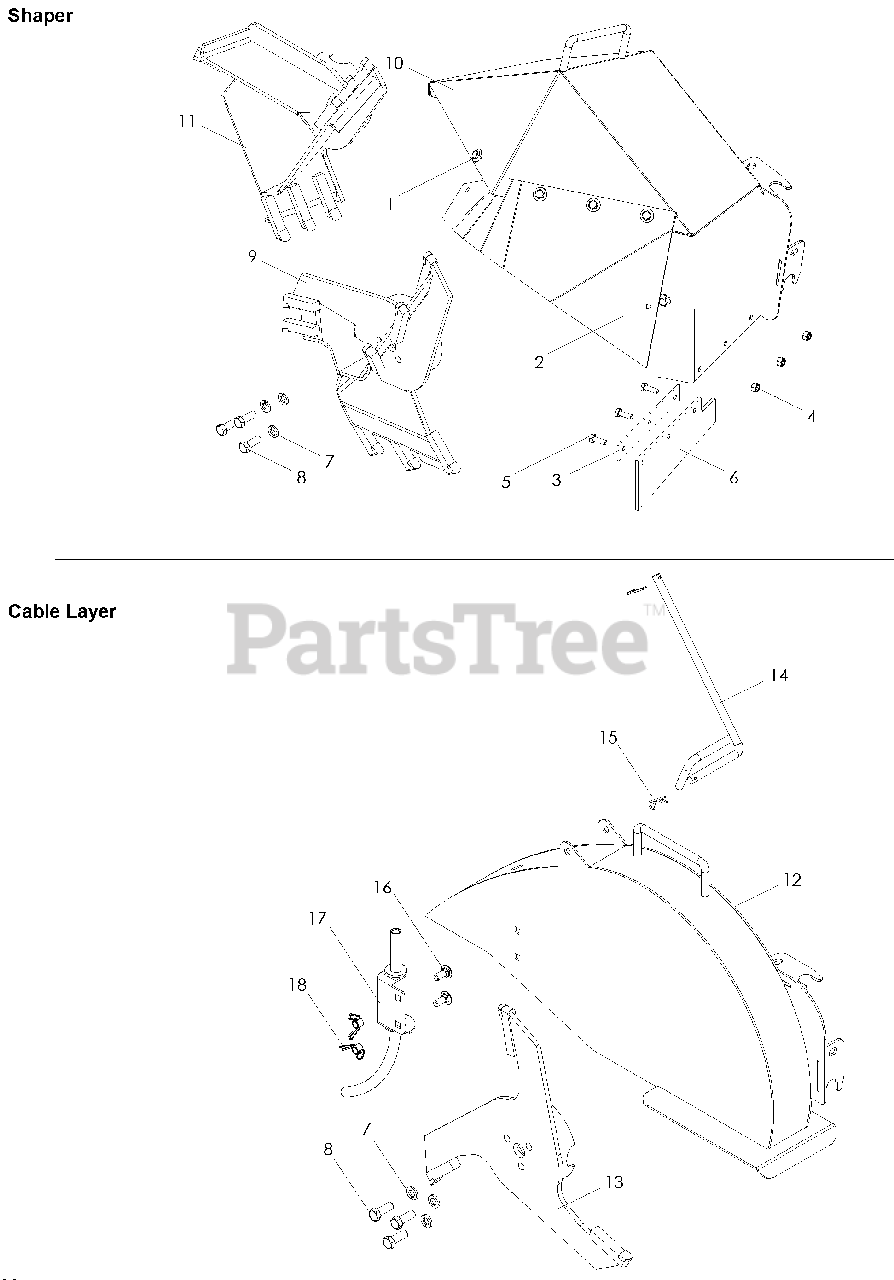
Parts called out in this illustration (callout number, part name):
1	WASHER 1/4 FLAT
2	FLAP, LARGE
4	NUT 1/4-20 HEX NYLOC
5	HCS 1/4-20 x 3/4
7	WASHER 3/8 SPLT LOCK
8	HCS 3/8-16 x 1
9	BLADE, SHAPER
10	GUARD, SHAPER
11	BLADE, PAVER
12	GUARD, W/DECALS
13	BLADE, CABLE
14	PIN, SPOOL
15	COTTER HAIRPIN
16	RHSNB 5/16-18 x 3/4
17	TUBE WLDMT
18	WING NUT 5/16-18 UNC
